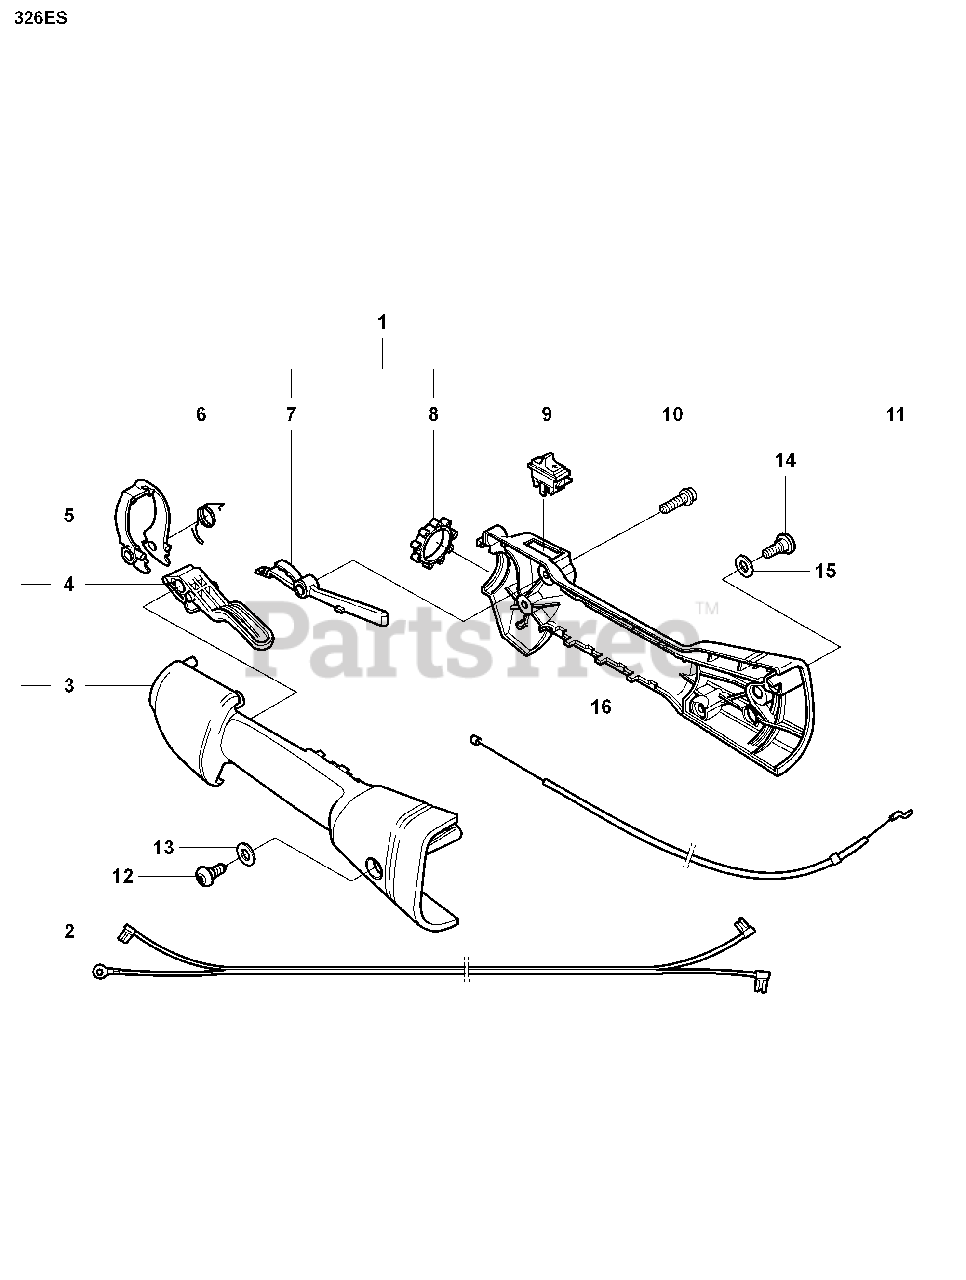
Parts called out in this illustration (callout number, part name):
2	SHORT-CIRCUIT CABLE
3	HANDLE HALF HSG LH
3	HANDLE
4	THROTTLE TRIGGER
7	THROTTLE LOCK
8	VIBRATION DAMPER
9	STOP BUTTON
11	THROTTLE CABLE
12	SCREW MT5X11
13	O-RING 8X1.6
14	SCREW MT5X11
15	O-RING 8X1.6
16	HSG THROTTLE RH
16	HANDLE
